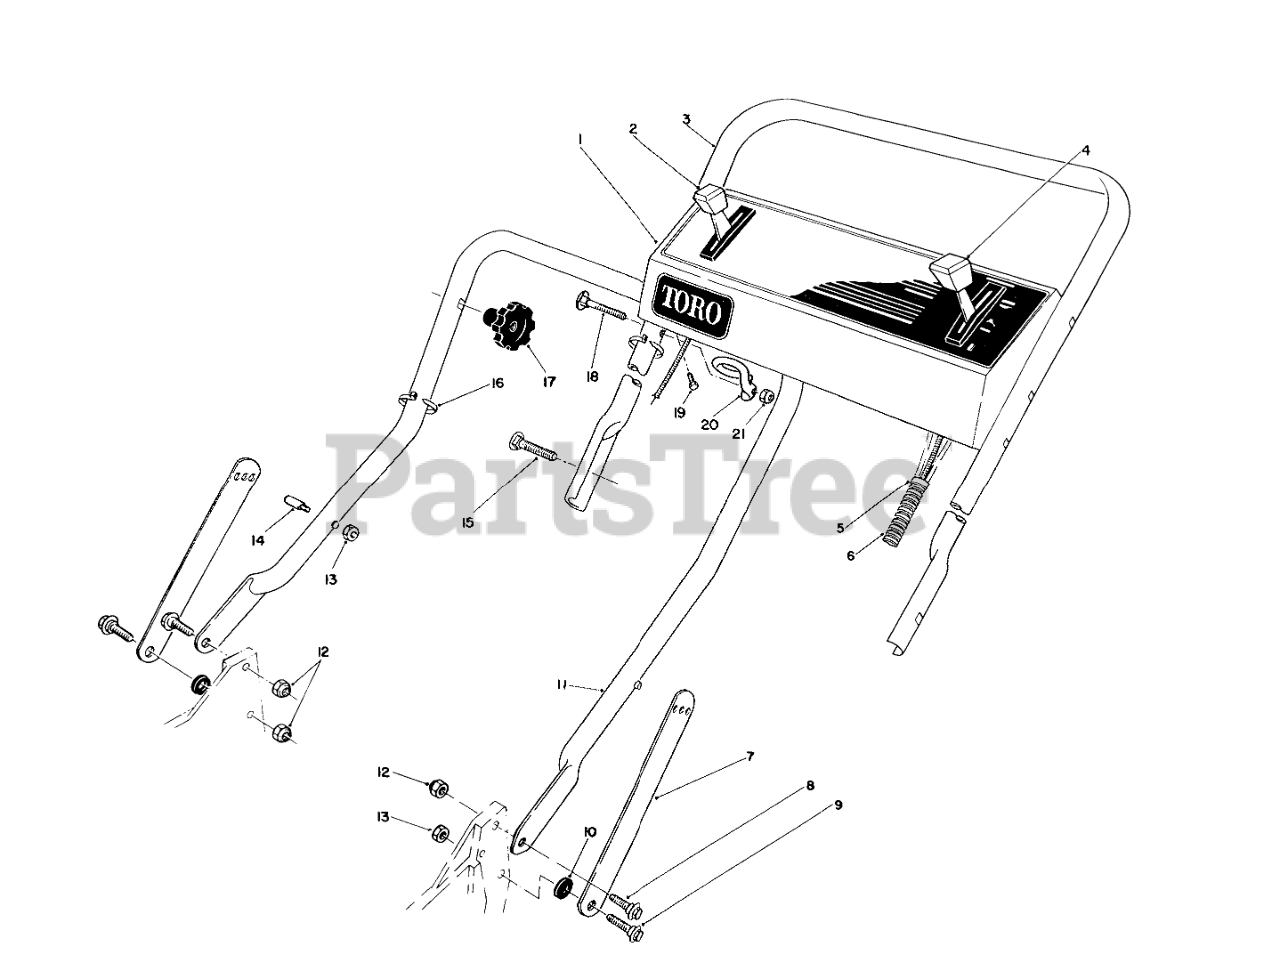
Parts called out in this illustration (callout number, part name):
1	Panel-Control
2	GROUND SPEED CONTROL
3	UPPER HANDLE
4	THROTTLE CONTROL - R&S
5	FITTING-RING
6	CONTROL CABLE COVER
7	Handle Latch
8	SCREW-SHOULDER
9	SCREW-SHOULDER
10	SPACER
11	LOWER HANDLE ASM
12	NUT-LOCK, NI
13	NUT-LOCK, NI
14	HANDLE PIN
15	5/16-18 X 2 HNDLE SCREW
16	TIE-CABLE
18	HANDLE SCREW
19	SCREW-HWHTF
20	Guide
21	NUT-LOCK, NI
